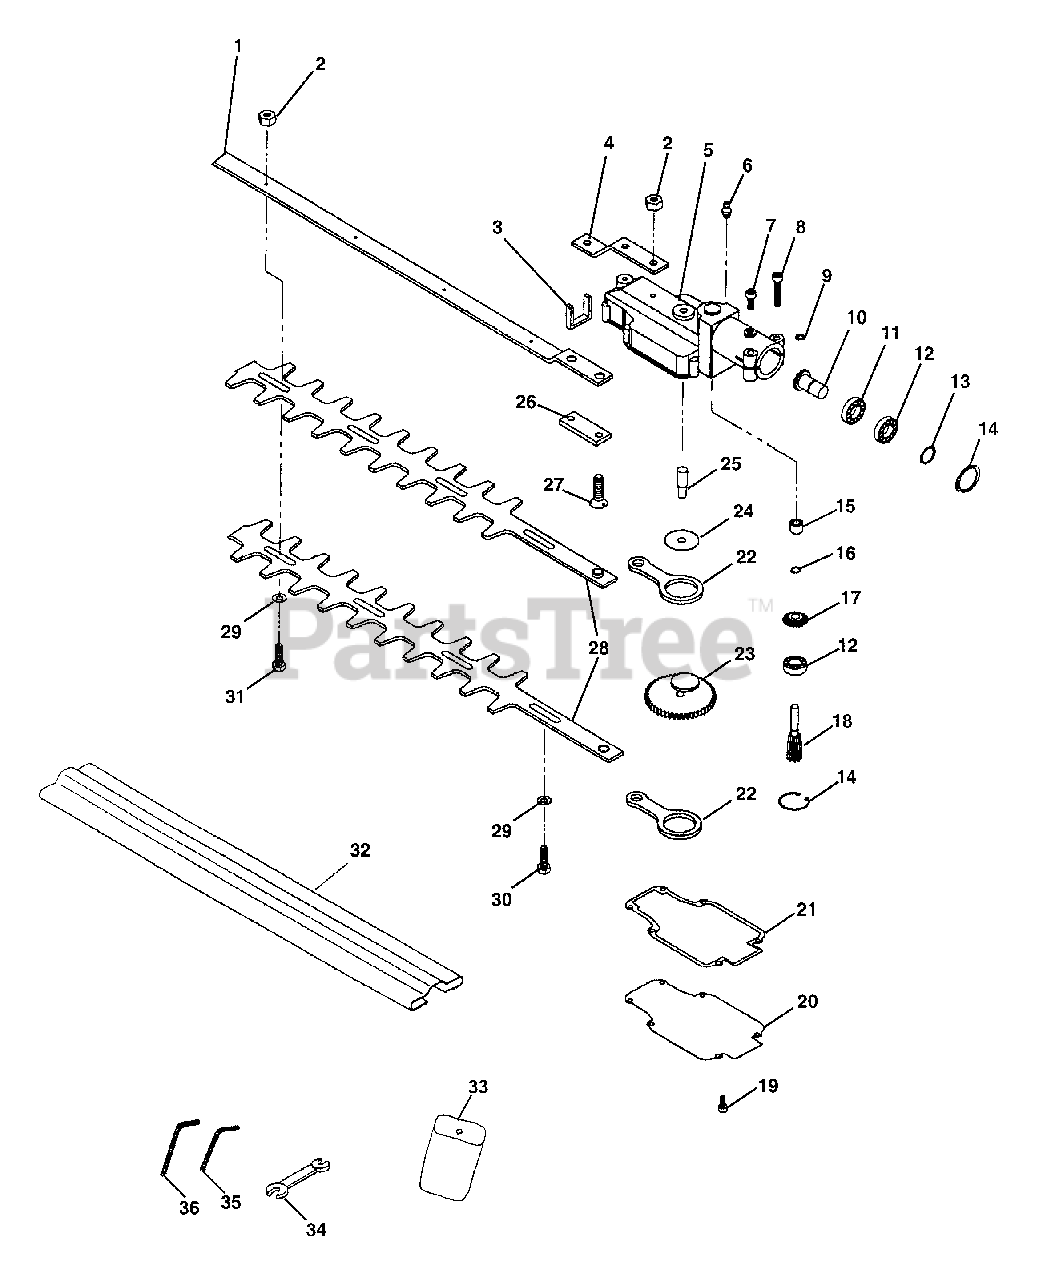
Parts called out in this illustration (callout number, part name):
1	SUPPORT, BLADE - 20" (50cm)
2	LOCKNUT - 6
3	SEAL, FELT
5	CASE, GEAR
6	FITTING, GREASE
7	SCREW - 5X12
8	SCREW - 5X28
10	GEAR
11	BEARING, BALL - 6901Z
12	BEARING, BALL - 6901
13	RING, RETAINING - 12
14	RING, RETAINING - 24
15	BEARING, NEEDLE
16	RING, RETAINING
17	GEAR - BEVEL -- DRIVEN
18	GEAR - SHAFT
19	SCREW - 4X12
20	LID, GEAR CASE
21	GASKET, GEAR CASE
22	ROD, CONNECTING
23	GEAR - DRIVE
25	DRIVESHAFT
27	SCREW - 6X35
28	BLADE - 20" (50cm)
29	WASHER - 6
32	COVER, BLADE
33	BAG, TOOL
34	SPANNER - 8X10mm
35	HEX KEY - 3mm
36	HEX KEY - 4mm
